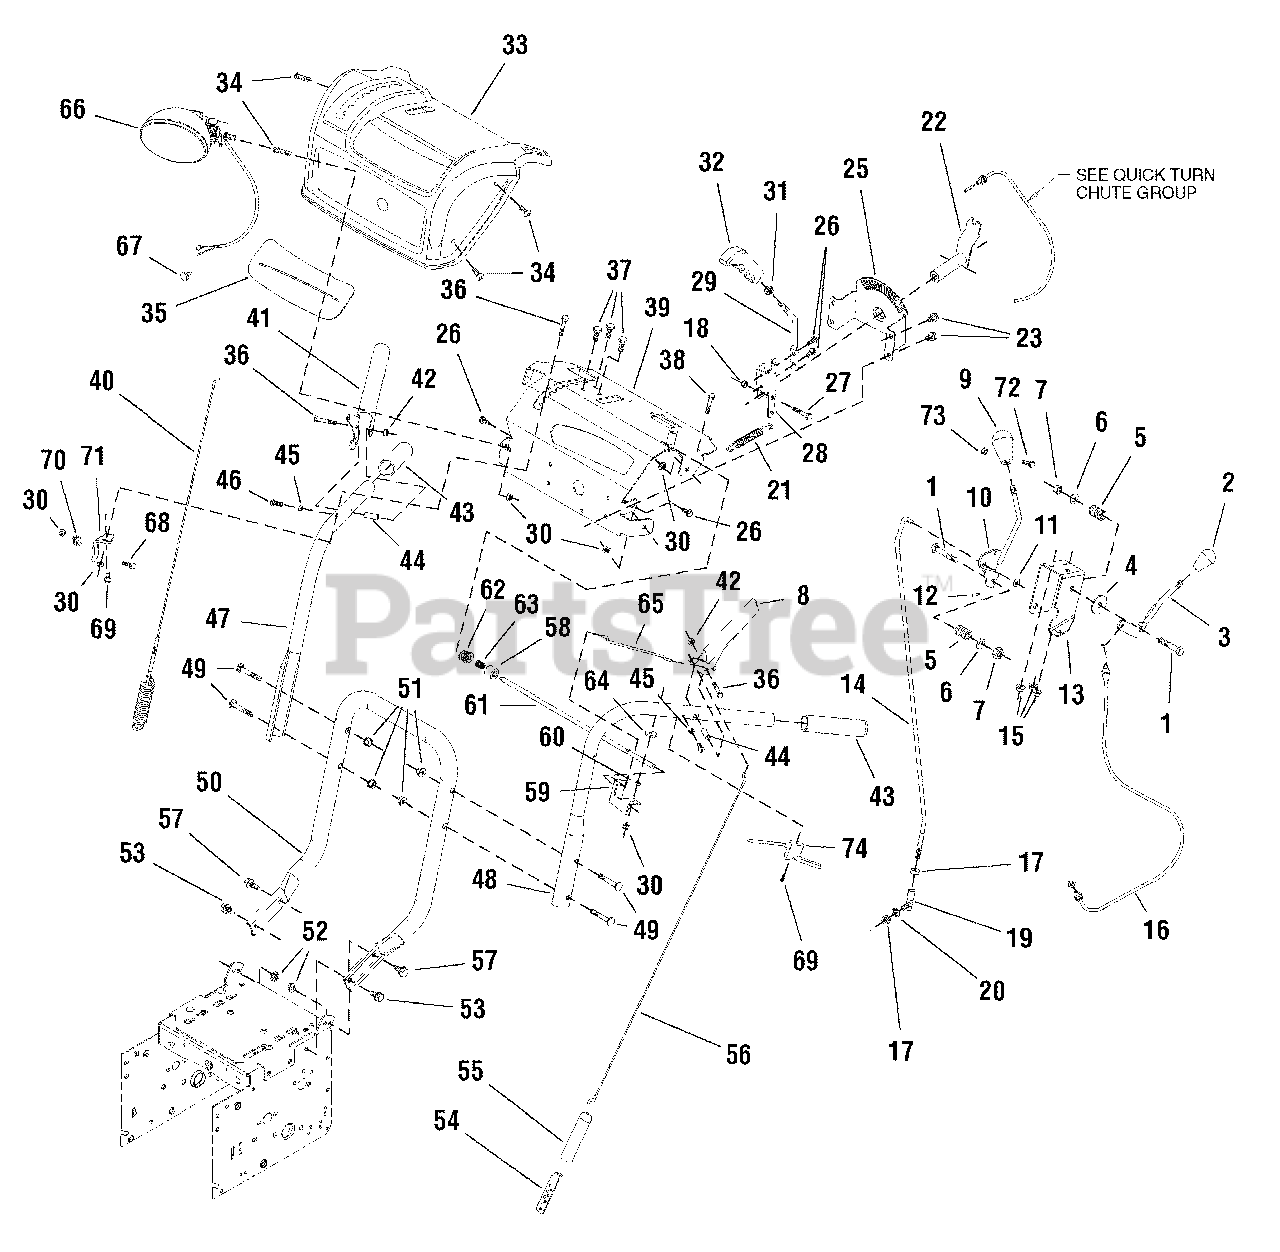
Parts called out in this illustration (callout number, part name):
1	CAPSCREW, Hex Head 3/8-16 x 2 G5
2	KNOB, Interior Thread 3/8-16
4	WASHER, 3/8
5	SPRING
6	WASHER, 3/8
7	NUT, Hex Lock ESNA Light 3/8-16NC3B
8	GRIP, Clutch, L.H.
9	KNOB, Slot Speed
10	ROD & PLATE ASSEMBLY, Speed Control
11	WASHER, 5/16
12	COTTER PIN
13	BRACKET, Trac & Deflector Control
14	ROD, 5/16-24 x 1.27
15	NUT, Hex Flange 5/16-18, Whiz Lock
16	CABLE, Deflector Control
17	NUT, Hex 5/16-24
18	NUT, Hex Flange 1/4-20 Centerlock
19	BALLJOINT, Steel
20	LOCKWASHER, Spring 5/16
21	SPRING, Extension
22	TUBE & BRACKET ASSEMBLY, Cable Support
23	SCREW, Hex Washer Head Taptite 5/16-18 x 1/2
25	SUPPORT, Chute Control
26	SCREW, Hex Washer Head Taptite 1/4-20 x 5/8
27	BOLT, Shoulder 1/4-20
28	BRACKET, Support Quick Turn
29	ROD, Chute, 3/8-16 x 1
30	NUT, Hex Lock ESNA Light 1/4-20 NC3B
31	NUT, Hex Jam 3/8-16 NC2B
32	GRIP, Lever 3/8-16 Long
33	COVER, Panel
34	SCREW, Truss Head Torx Drive 1/4-20 x 3/4
35	BELLOWS, Black Rubber Quick Turn
36	CAPSCREW, Hex Head 1/4-20 x 1-1/2 G5
37	CARRIAGE BOLT, 5/16-18 x 3/4 G5
38	CAPSCREW, Hex Head 1/4-20 x 1-3/4 G5
39	SUPPORT, Dash Panel Cover
40	CABLE & SPRING ASSEMBLY, Auger Drive R.H.
41	GRIP, Clutch, R.H.
42	NUT, Hex Centerlock 1/4-20
45	SPACER
46	SCREW, Pan Head Torx 1/4-20 x 3/4 Taptite
47	HANDLE, Upper R.H. Tubular
48	HANDLE, Upper L.H. Tubular
49	CARRIAGE BOLT, 5/16-18 x 2-1/4 G5
50	HANDLE, Lower Tubular
51	NUT, Hex Flange 5/16-18 ESNA
52	NUT, Hex Flange 5/16-18 Two-Way Lock
53	SCREW, Hex Washer Head Taptite 5/16-18 x 3/4
54	BRACKET, Cable Adjusting
55	BOOT, Control Spring
56	CABLE, Front Drive
57	CAPSCREW, Hex Head 5/16-18 x 1 G5
59	BRACKET, Free Hand Control
60	SPACER, Powdered Metal
61	ROD & SPRING ASSEMBLY W/ PIN
62	WASHER, 1/2
63	SPRING, Compression
64	WASHER, 1/4
65	ROD, Hold Down
66	HEADLIGHT ASSEMBLY, Oval Amber
67	FASTENER, Panel
68	CARRIAGE BOLT, 1/4-20 x 1-1/4 G5
69	SCREW, Pan Head Torx #10 x 1/2
70	SPOOL CABLE, Auger Control
71	BRACKET, Spout Cable
72	SCREW, Round Head Phillips #10-24 x 3/4
73	NUT, Hex Lock 10-24 w/Nylon Insert
74	CABLE & HANDLE ASSEMBLY
